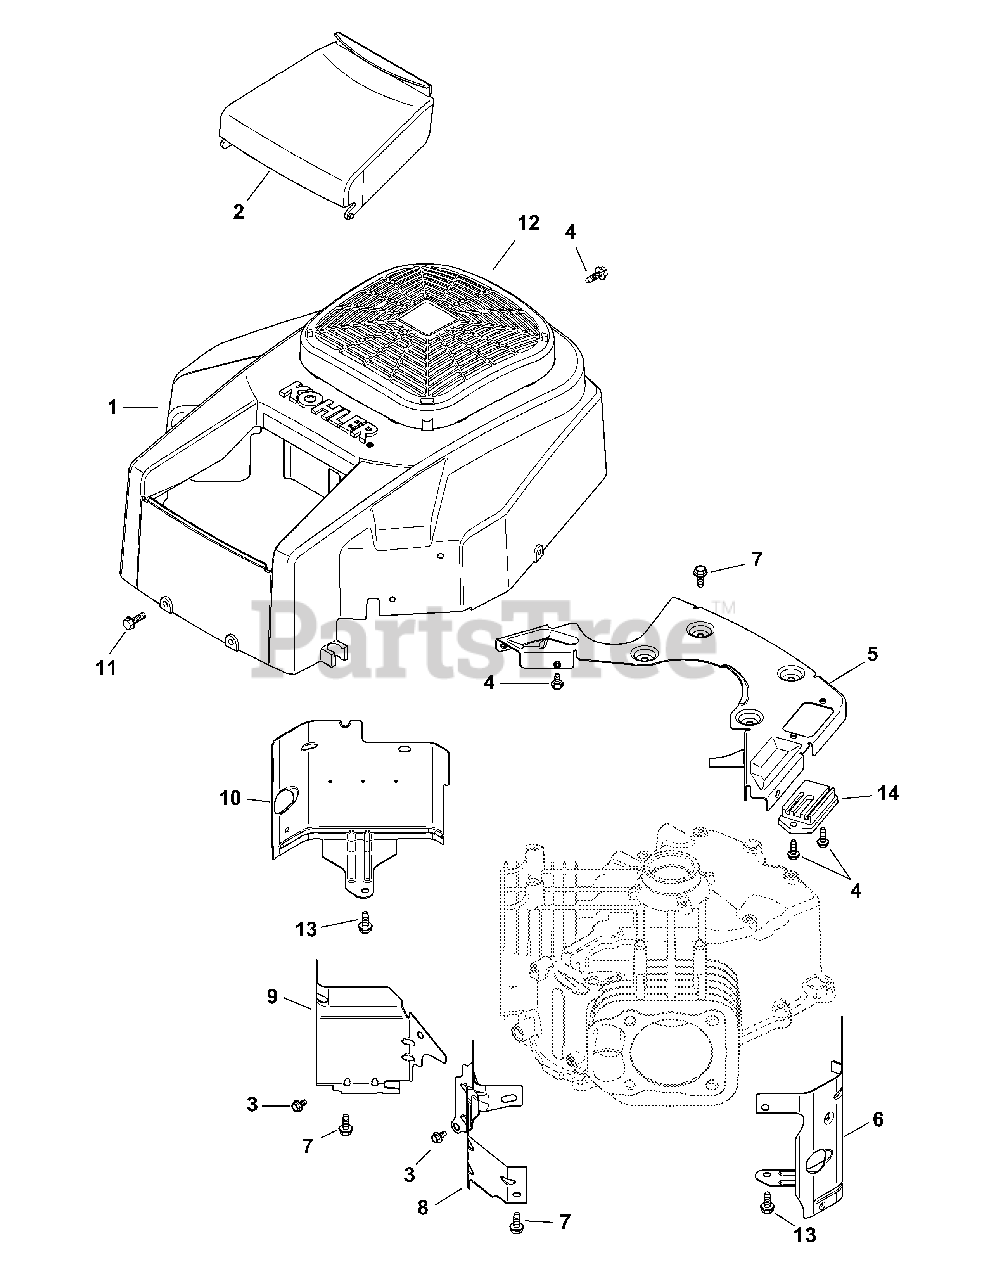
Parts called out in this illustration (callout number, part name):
1	Blower Housing Kit
2	Air Cleaner Cover
3	Flange Screw, M5 x .8 x 10
4	Flange Screw, M5 x .8 x 16
5	Backing Plate Kit
6	Cylinder Barrel Baffle, #2 Side
7	Flange Screw, M6 x 1.0 x 16
8	Valley Baffle, #2 Cylinder
9	Valley Baffle, #1 Cylinder
10	Cylinder Barrel Baffle, #1 Side
11	Screw, M6 x 1.7 x 18
13	Flange Screw, M6 x 1.0 x 10
14	Regulator/Rectifier
